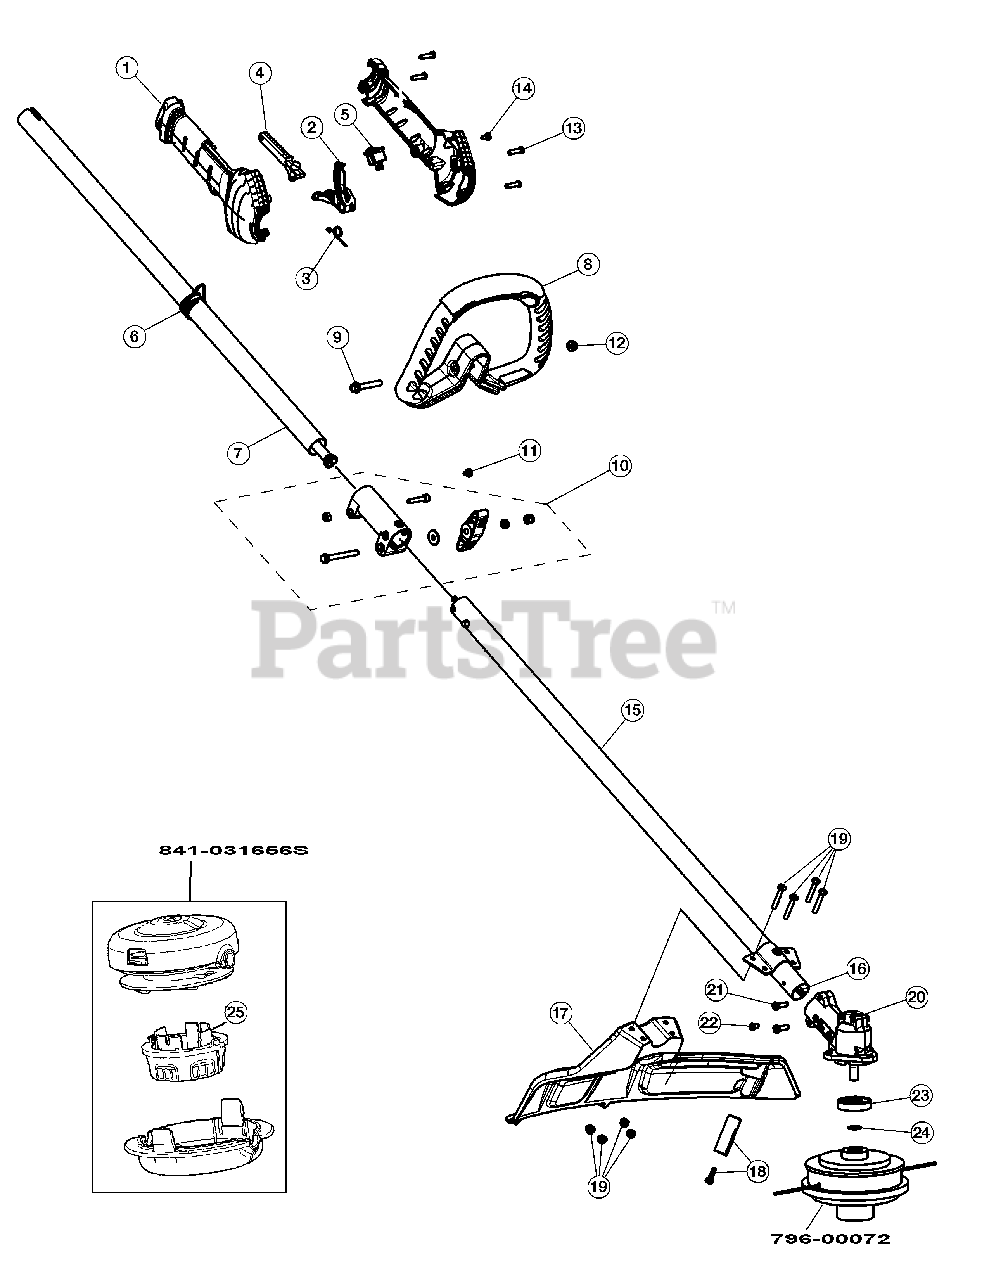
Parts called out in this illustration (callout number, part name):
1	Grip Assembly (Incl. 2 - 5, 13 and 14)
2	Throttle Trigger
4	Throttle Lockout
6	Shoulder Strap Clip
7	Upper Drive Shaft Housing
8	Handle Assembly (Incl. 9 and 12)
10	Split Boom Coupler (Incl. 11)
11	Coupler Anti-Rotation Screw
14	Grip Anti-Rotation Screw
15	Lower Drive Shaft Housing Assembly (Incl. 16)
16	Lower Flexible Drive Shaft
17	Shield Assembly (Incl. 18)
18	Blade Assembly
19	Shield Mounting Screw and Nut
20	Gearbox (Incl. 21 - 25)
21	Gearbox Mounting Hardware
22	Anti-Rotation Screw
23	Cutting Head Driver
796-00072	Cutting Head Assembly
841-031656S	Cutting Head Assembly
